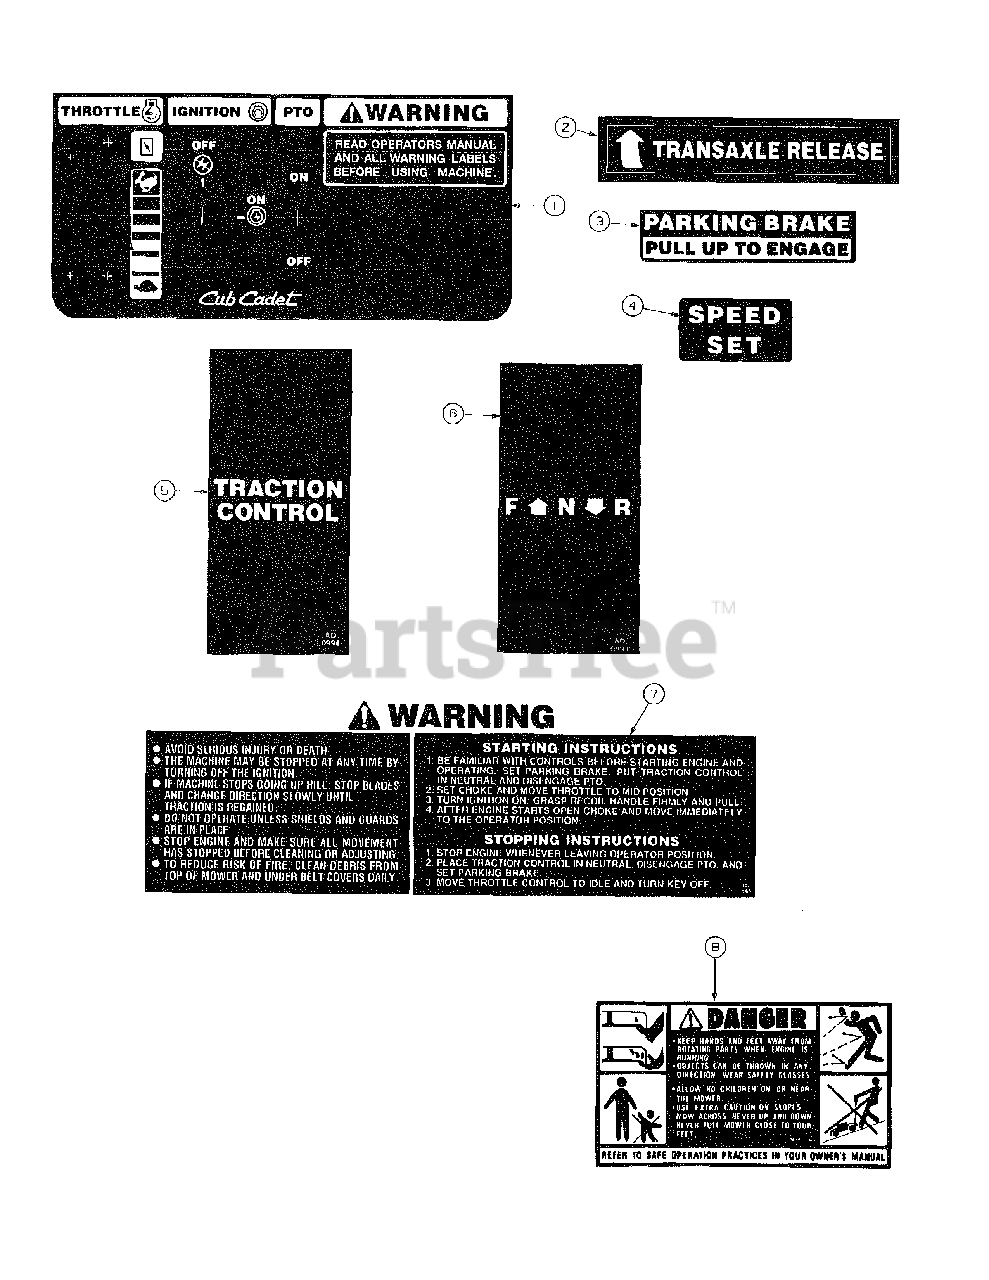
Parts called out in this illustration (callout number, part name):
1	Graphic, Control Panel
2	Graphic, Transaxle Release
3	Graphic, Park Brake
4	Graphic, Speed Set
5	Graphic, Traction Control
6	Graphic, F-N-R
7	Graphic, Warning
8	Graphic, Danger
